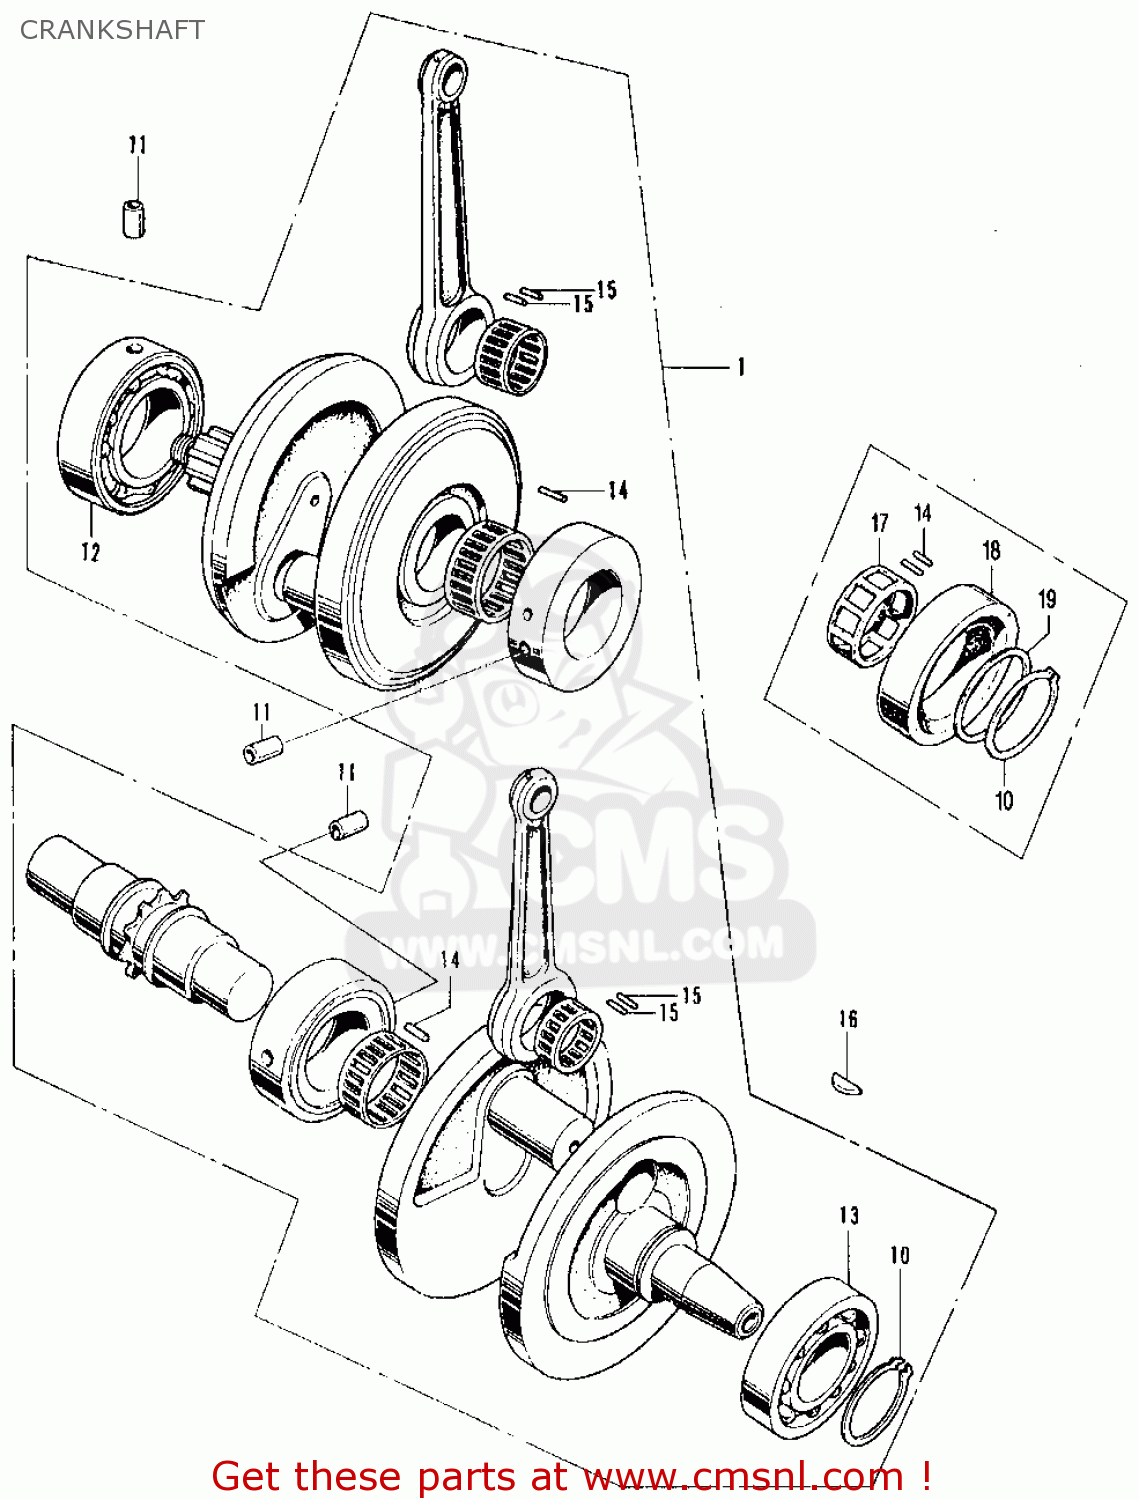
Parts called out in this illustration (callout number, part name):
1	CRANKSHAFT
10	CIR CLIP,30MM
11	PIN,DOWEL 7X12
12	B/BRG RAD N/COM
13	B/BRG RAD N/COM
14	ROLLER 4X10
16	KEY, WOODRUFF
17	RETAINER,L MAIN
18	OUTER,L BEARING
19	WASHER (30MM)
